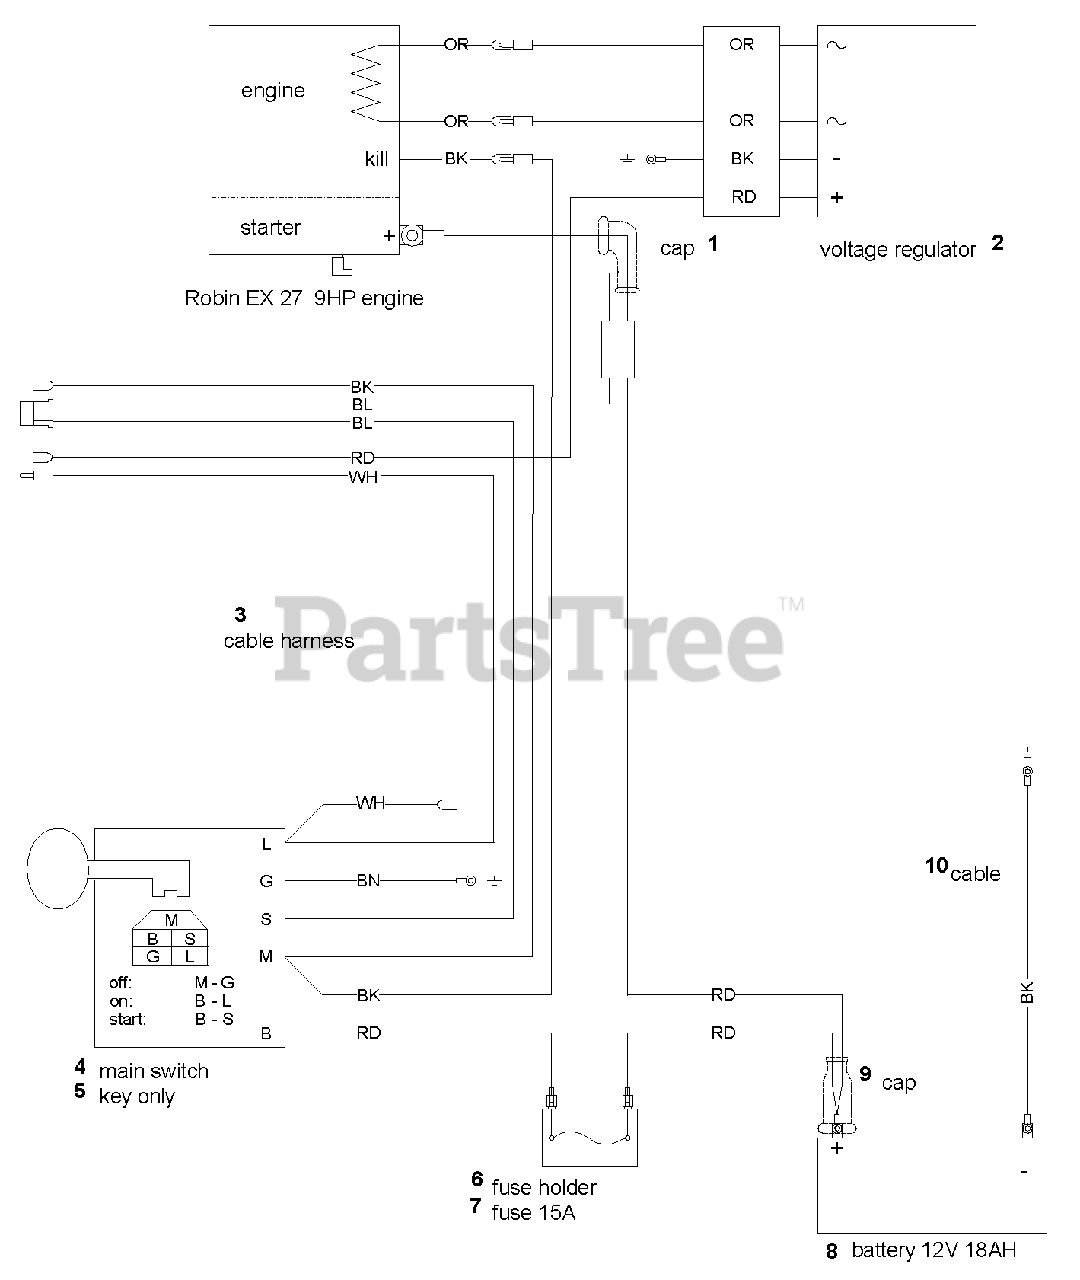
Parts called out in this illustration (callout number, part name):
2	Regulator, AC
3	Cable Harness
4	Assembly, Starter Switch
5	Assembly, Key
6	Fuse Holder
7	15A, Fuse
8	Battery, Rapid
10	Cable Black
